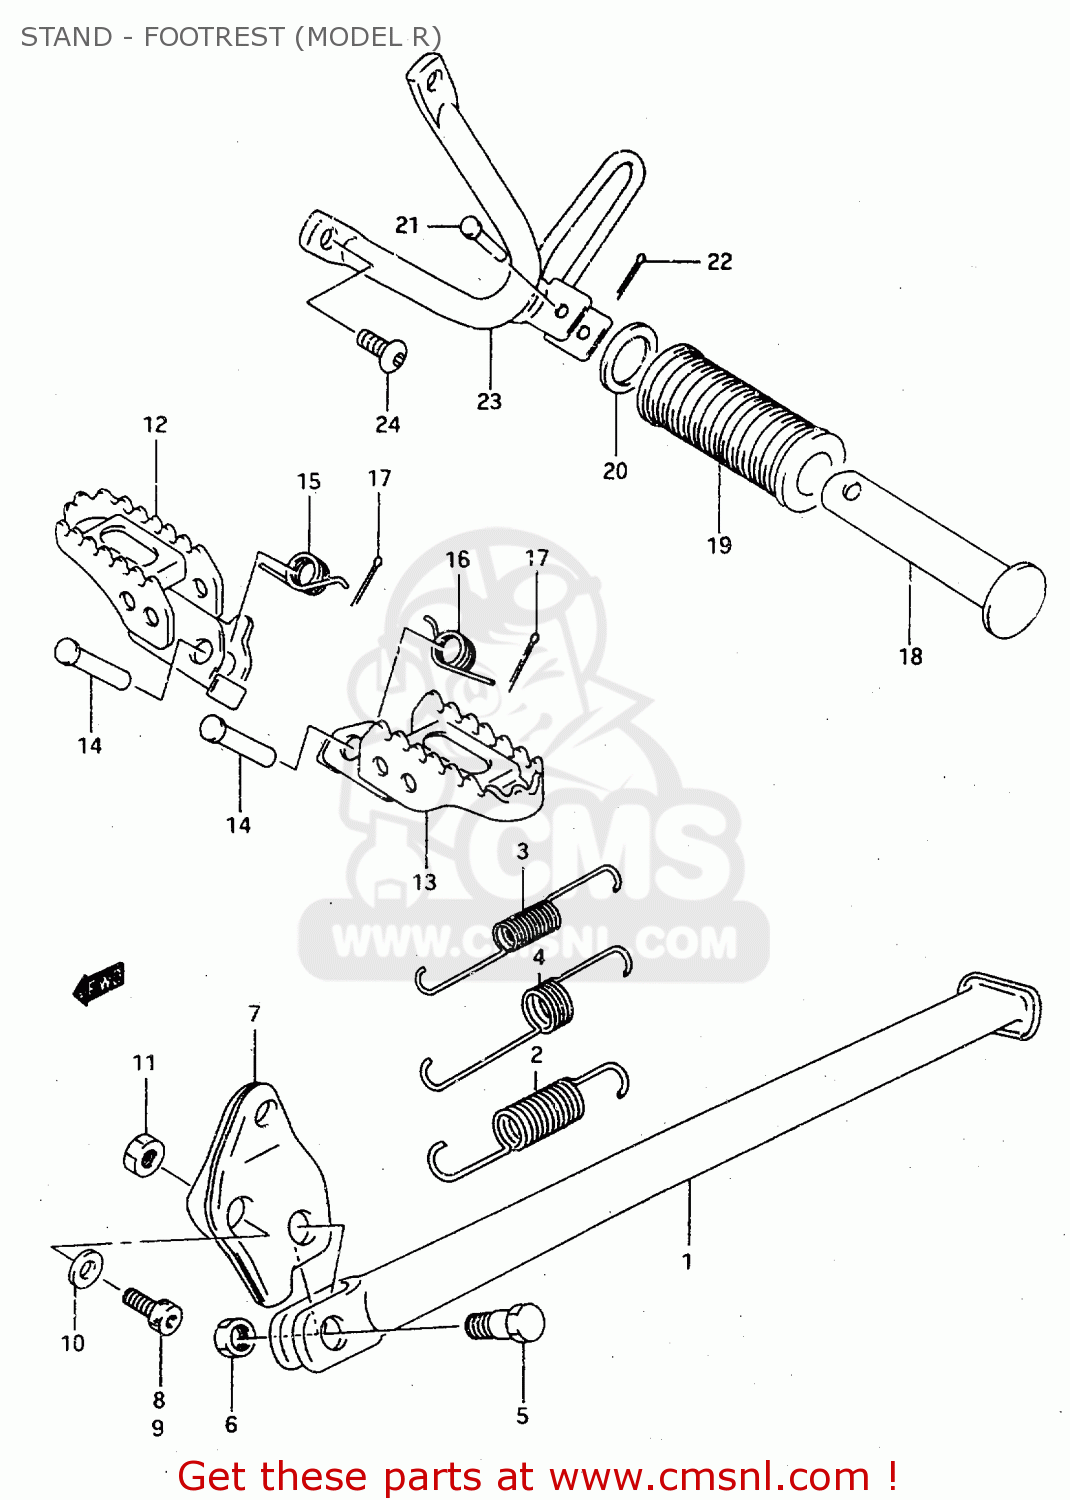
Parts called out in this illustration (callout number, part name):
1	STAND, PROP (BLACK)
2	SPRING
3	SPRING
4	SPRING
5	BOLT L:30
6	NUT
7	BRACKET, PROP STAND (BLACK)
8	BOLT(8X25)
9	BOLT(8X20)
10	WASHER
11	NUT
12	FOOTREST,FR,R
13	FOOTREST,FR,L
14	PIN
15	SPRING
16	SPRING LH
17	PIN 25X20
18	BAR,FOOTREST RUBBER
19	RUBBER,PILLION FOOTREST
20	WASHER (19.5X32X2)
21	PIN
22	PIN 20X20
23	BRACKET,PILLION FOOT,R(BLACK)
24	BOLT
